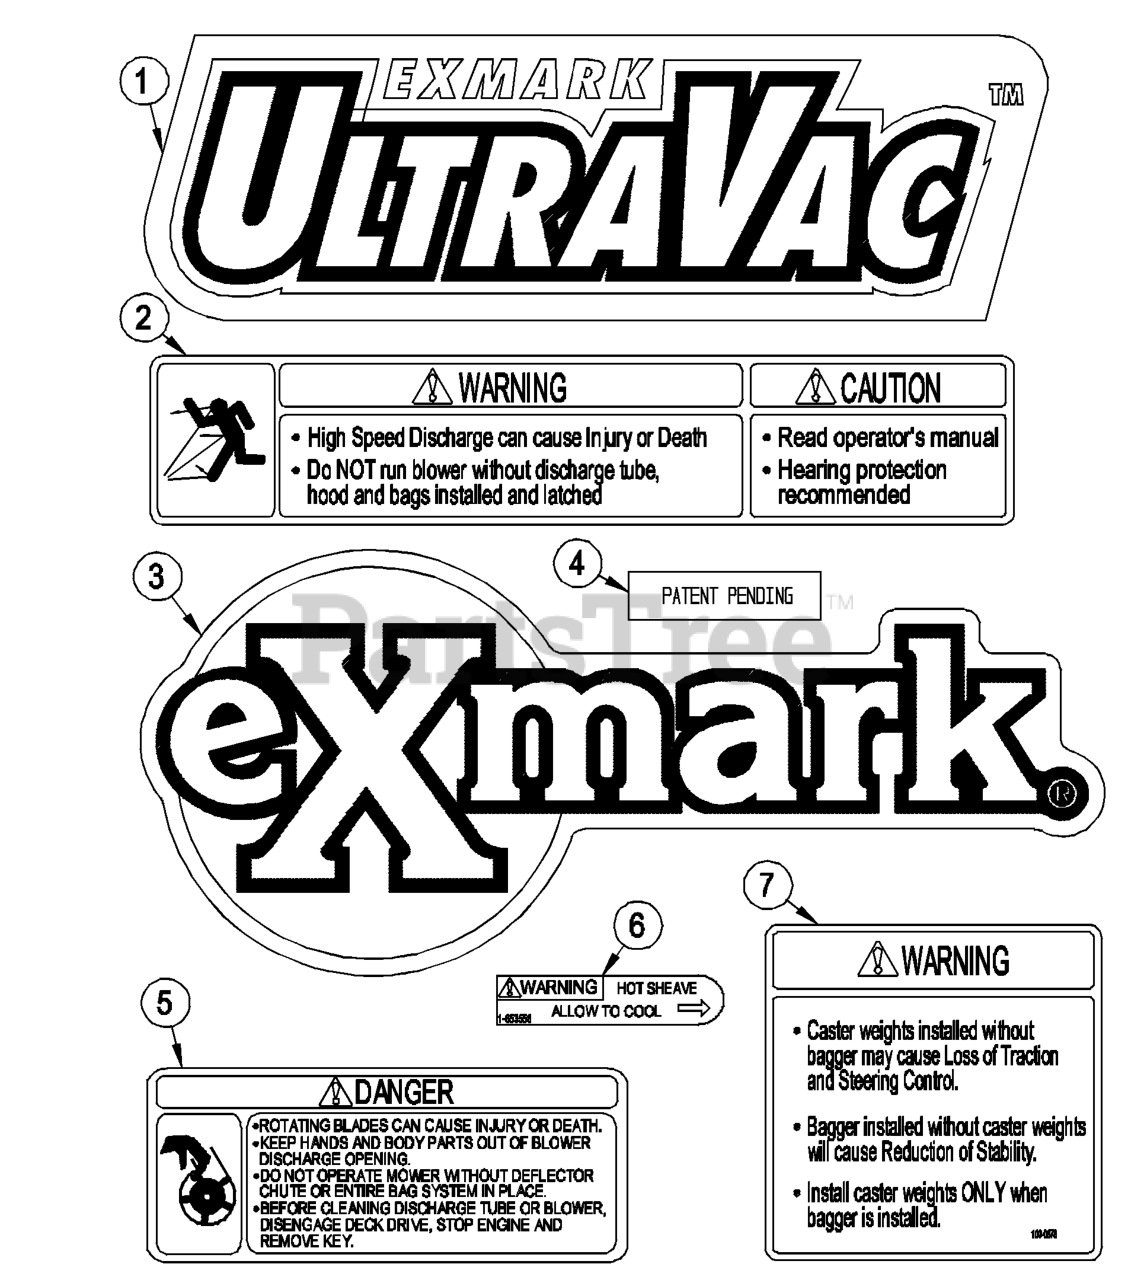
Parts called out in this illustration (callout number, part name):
1	DECAL, ULTRAVAC
2	DECAL, IMPELLER WARNING
3	DECAL, EXMARK LOGO
4	Decal, Patent Pending
5	DECAL,DISCHARGE WARNING
6	DECAL-WARNING
